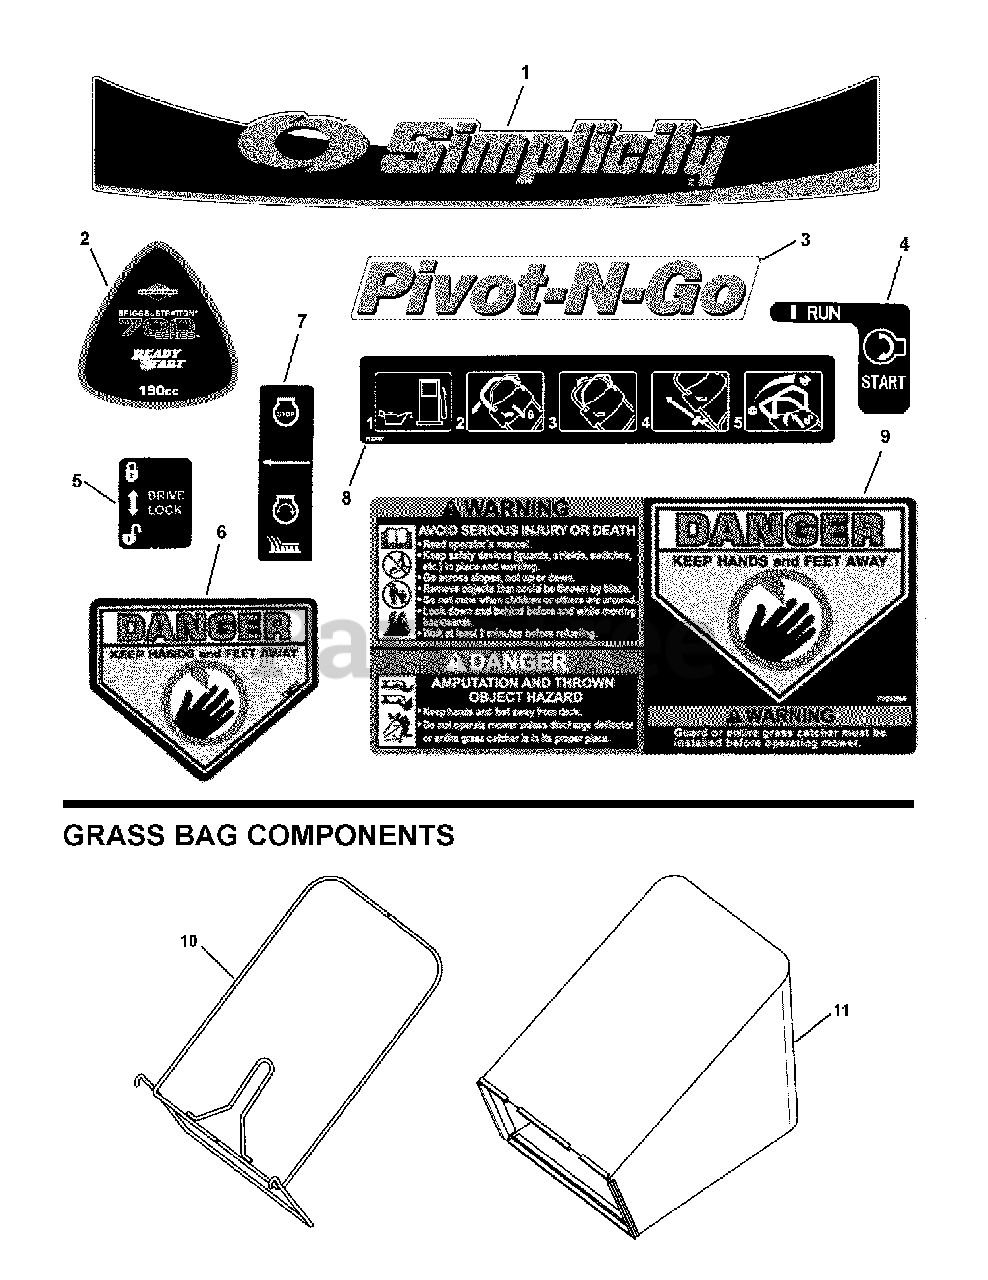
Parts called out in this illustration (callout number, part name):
1	DECAL, Simplicity Walk Mower, Steel deck
2	DECAL, 700 Series Engine, Simplicity
3	DECAL, Pivot-n-Go, Simplicity
4	DECAL, Ignition Switch
5	DECAL, Neutral lock
6	DECAL, CPSC, Danger, Cut Finger
6	DECAL, CPSC, Cut Finger, French/English
7	DECAL, OPC Bail International Symbol
8	DECAL, Pivot, Handle
9	DECAL, Warning, Rear Discharge Door
9	DECAL, Warning/Danger, FR/ENG, Rear Discharge Door
10	BAG FRAME - 21" Rear Discharge WBM
11	GRASSBAG, 21" Rear Discharge WBM
